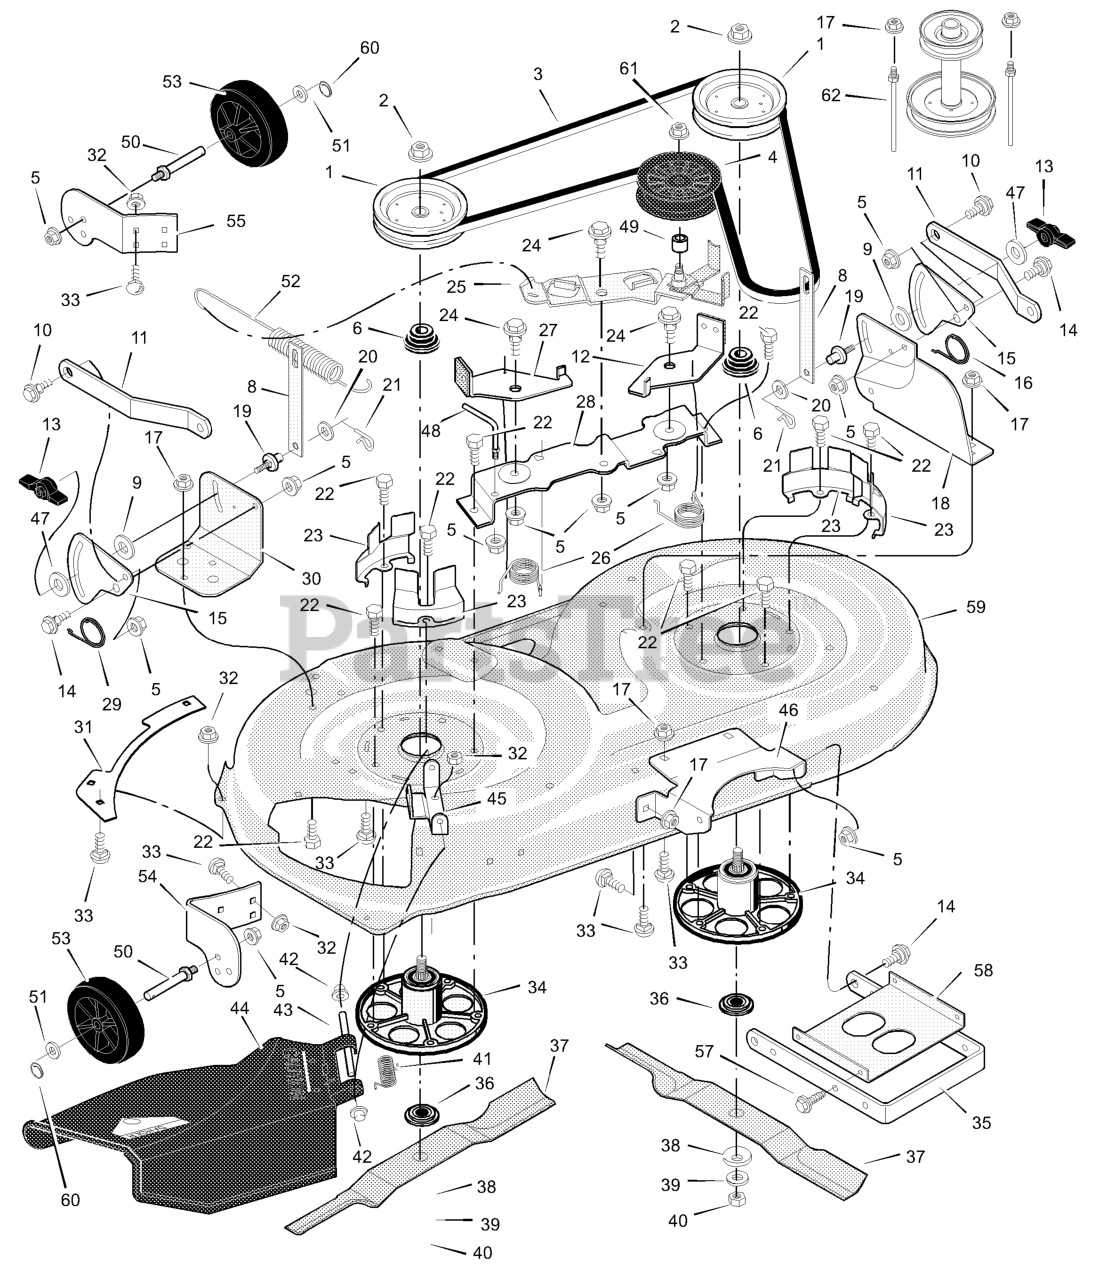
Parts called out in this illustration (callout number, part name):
1	Pulley, Jackshaft
2	Nut, Hex
3	Belt, Mower Drive
4	Pulley, Idler
5	Nut, Flange
6	Spacer, Pulley
8	Link, Lift
9	Pad, Friction
10	Bolt, Shoulder
11	Bracket, Suspension
12	Pad Assembly, Left Brake
13	Knob
14	Bolt, Shoulder
15	Plate, Suspension
17	Nut, Flange
18	Bracket, Suspension
19	Pin, Hanger
21	Pin, Hair
22	Bolt
23	Cover, Pulley
24	Bolt, Shoulder
25	Arm, Idler
27	Pad Assembly, Right Brake
28	Bracket, Brake
30	Bracket, Suspension
32	Nut, Flange
33	Bolt, Carriage
34	Mandrell Housing
35	Bracket, Suspension
36	Adapter, Blade
42	Cap, Push On
43	ROD, Deflector
44	Deflector Assembly
45	Bracket, Deflector Hinge
46	Bracket, Front Hanger
48	Guide, Belt
50	BOLT, Gauge Wheel
52	Spring, Extension
53	Wheel, Gage
54	Bracket, Right Wheel
55	Bracket, Left Wheel
58	Stiffener
59	Housing, Blade
60	Ring, Locking
61	Nut, Flange
62	Guide, Belt
